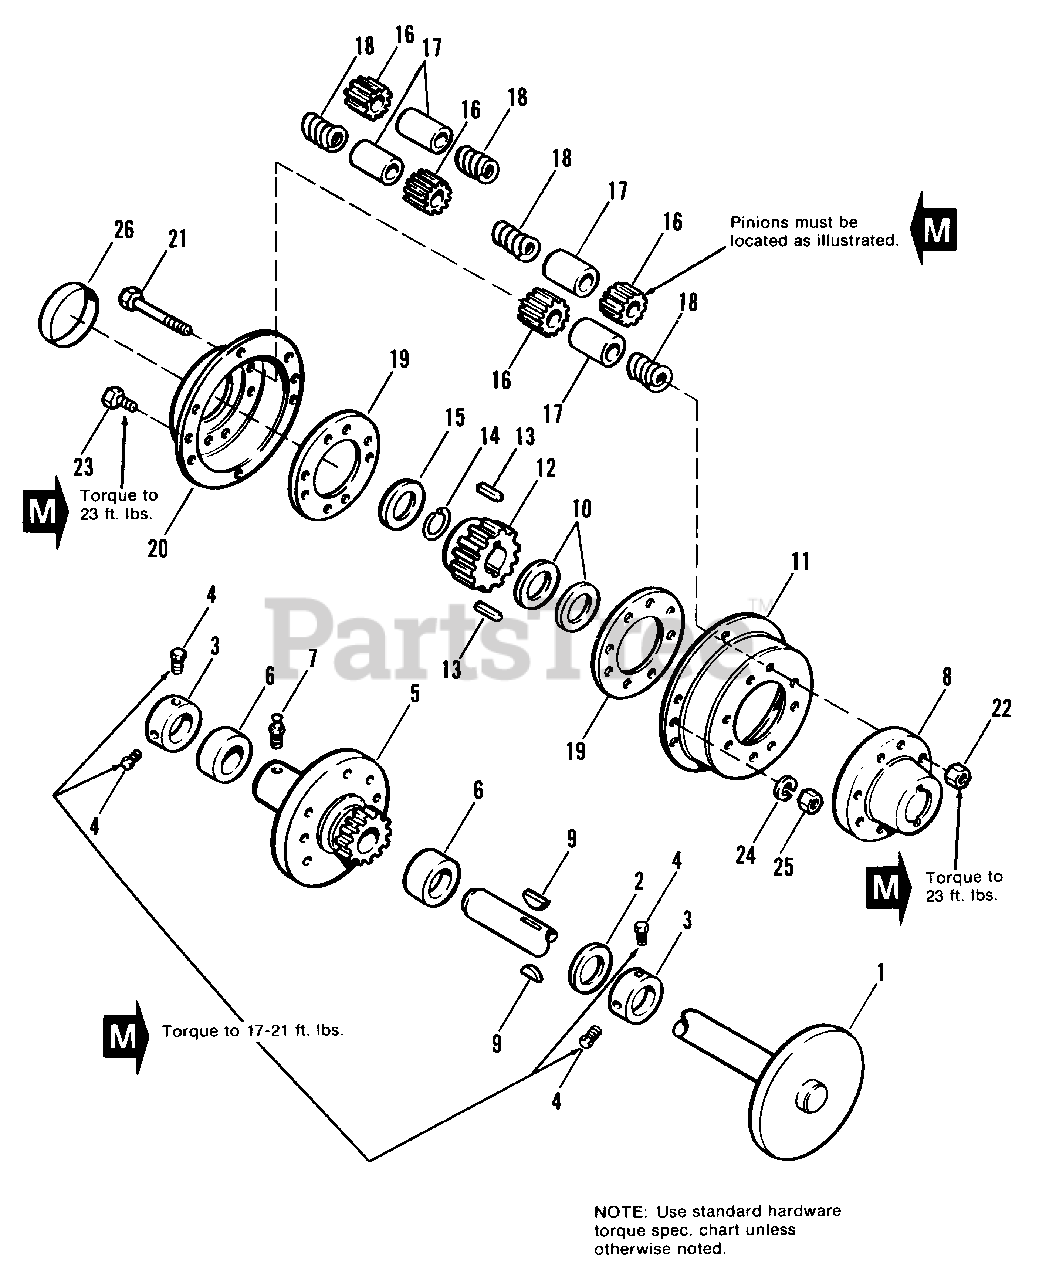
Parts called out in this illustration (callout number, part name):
1	REAR AXLE ASSY.
3	COLLAR, Set
4	SETSCREW, Sq. Hd., 5/16-18 x 1/2
5	R.H. WHEEL HUB ASSY.
7	FITTING, Grease
8	CARRIER, Diff.
10	WASHER, Axle
11	COVER, Diff.
12	GEAR, Diff.
13	KEY, Hi Pro, 1/4 x 3/4
14	RING, Retaining
15	WASHER, Axle
16	PINION, Diff.
17	SPINDLE, Diff. Pinion
19	RING, Spacer
20	COVER, Diff.
21	CAPSCREW, Hex Hd., 3/8-16 x 2-1/2
22	NUT, Hex, 3/8-16
23	CAPSCREW, Hex, 1/4-20 x 5/8
24	LOCKWASHER, 1/4
25	NUT, Hex, 1/4-14
26	SEAL, Cover
27	DIFFERENTIAL SUBASSY. (Includes Ref. No's. 8, 11, 16 thru 26)
